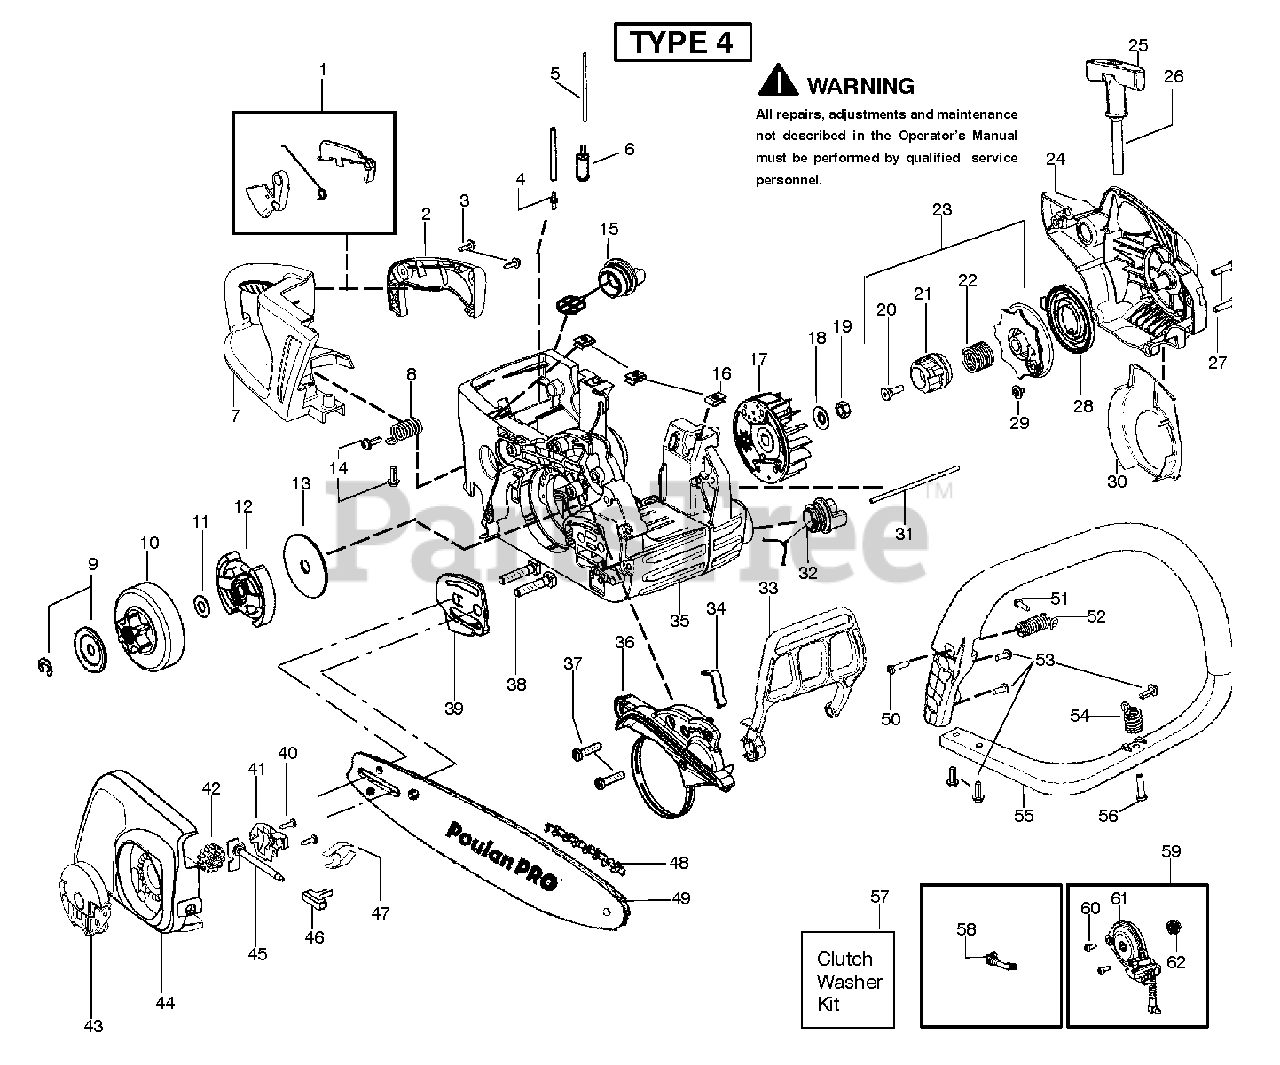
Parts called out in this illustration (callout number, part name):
1	KIT SAV TRIGGER & LOCKOUT
2	COVER HANDLE PPR GOLD OVERMOLD
4	FUEL LINE FITTING
5	KIT FUEL LINE
6	ASSY FUEL PICK UP W/LINE
7	HANDLE REAR PPGOLD OVERMOLD
8	SPRING ISOLATOR
10	ASSY CLUTCH DRUM 3/8
12	ASSY CLUTCH
13	WASHER CLUTCH LARGE
14	SCREW,FRONT HBAR 36/41
15	FUEL CAP ASSY W/RET
17	ASSY FLYWHEEL
18	WASHER-FLYWHEEL
19	NUT-FLYWHEEL
20	SCREW SHOULDER
21	HUB STARTER EPS
22	SPRING EPS
23	KIT EPS STARTER
24	Fan Housing
25	HANDLE STARTER
26	KIT-ROPE
27	SCREW M5.38-14X22.225MM
30	BAFFLE FLYWHEEL
31	ASSEMBLY-OIL-VENT
32	OIL TANK CAP
33	HANDGUARD CHAIN BRAKE
34	SPRING HANDGUARD
35	CHASSIS
36	KIT CHAIN BRAKE
37	SCREW M5.38-14X22.225MM
39	PLATE BAR MOUNTING
40	SCREW 6-19X.437
42	ASSY THUMB WHEEL BLACK
43	ASSY EZT KNOB PRO GOLD
44	HSG CLUTCH CVR EZT AV PRO GOLD
45	ADJUSTING SCREW
46	CHAIN TENSIONER PIN
48	ACCY-PLN CHN 16" 91VJ 56DL 3/8
49	BAR 16" SN 91 3/8 56DL
50	SCREW M5.38-14X22.225MM
51	M5.0X0.8X16 TT TRX SEMS
52	SPRING ISOLATOR ASSEMBLY
53	SCREW,FRONT HBAR 36/41
54	SPRING ISOLATOR ASSEMBLY
55	HANDLE FRONT
56	SCREW M5.38-14X22.225MM
57	KIT SAS CLUTCH WASHER
58	ASSY PICK UP OIL TANK
59	KIT OIL PUMP
60	SCREW 6-19X.437
61	ASSY OIL PUMP
62	WORM GEAR
